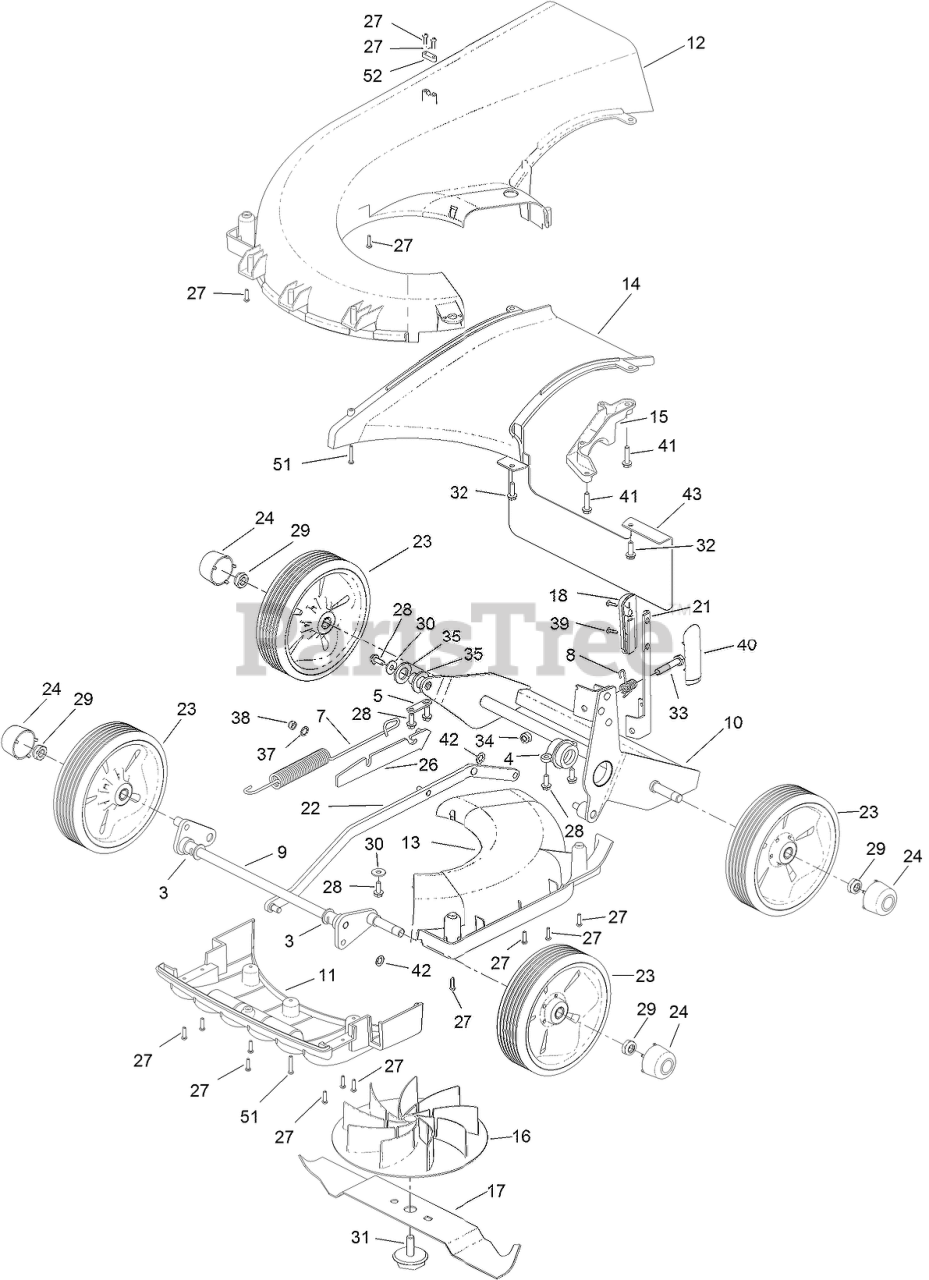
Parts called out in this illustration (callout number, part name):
3	BEARING-AXLE, FRONT
4	HOUSING-PIVOT BEARING, LH
5	PLATE-SECURING
7	SPRING-COUNTER BALANCE
8	SPRING-HOC
9	AXLE-FRONT
10	FRAME-WHEEL
11	MOULDING-FIN
12	MOULDING-SNAIL DECK
13	MOULDING-ACCESS, SNAIL DECK
14	MOULDING-THROW PLATE
15	MOUNT-BEARING
16	MOULDING-MOUNT, ELECTRIC BLADE
17	CUTTERBAR-ELECTRIC
18	KNOB-HOC, RH
21	LEVER-HOC
22	ROD-CONNECTING BAR
23	WHEEL ASM
24	CAP-WHEEL, CENTER
26	MOUNT-SPRING
28	SCREW-TAPTITE
29	NUT-NYLOC
30	WASHER
31	BOLT-FIXING, BLADE
32	SCREW-TAPTITE
34	NUT-HEX, NI
35	WASHER-PLAIN
37	WASHER-PLAIN
38	NUT-NYLOC
40	KNOB-HOC, LH
41	SCREW-HH
42	WASHER-STARLOCK
43	GUARD-REAR
52	CLAMP-CABLE
